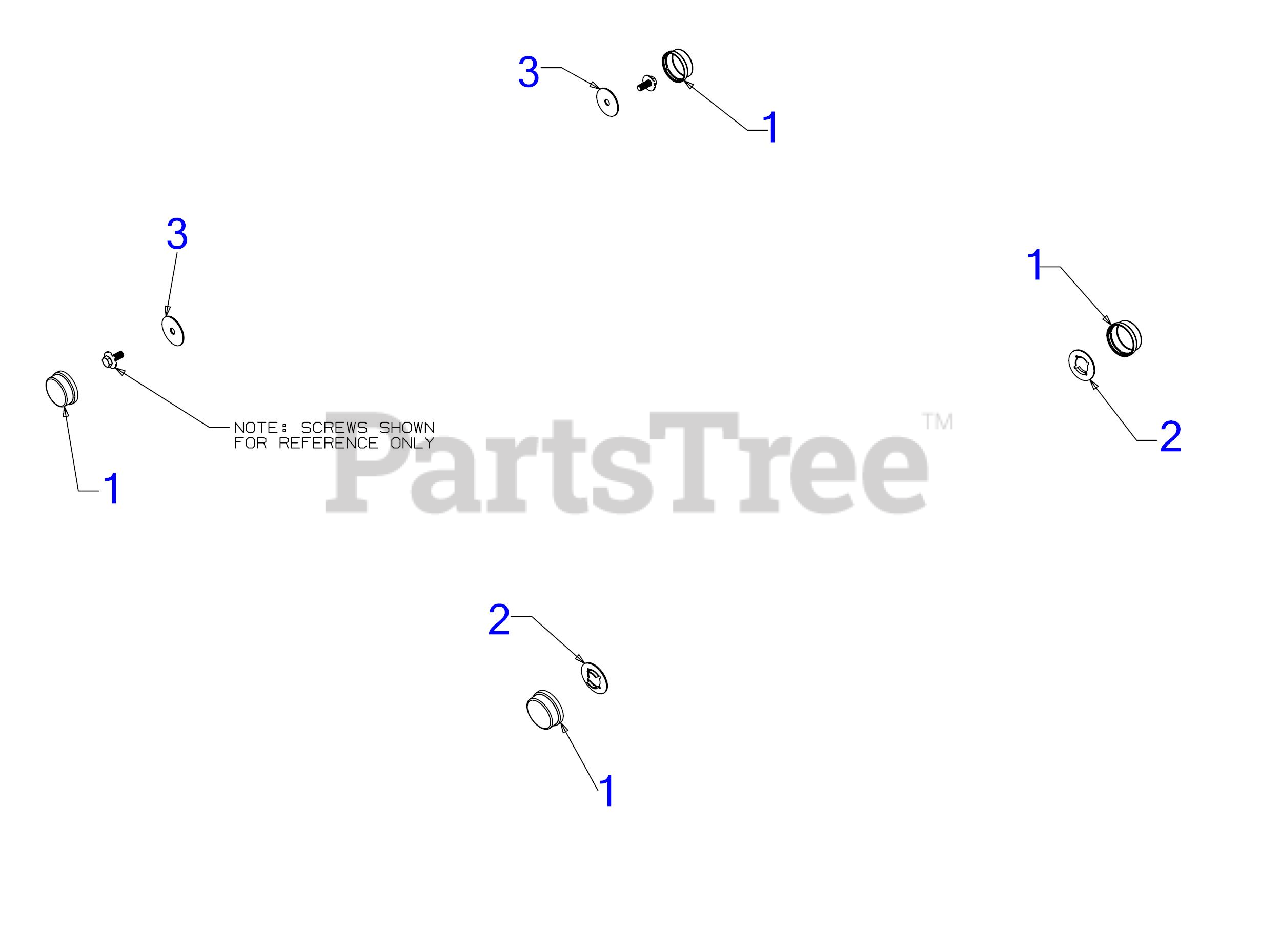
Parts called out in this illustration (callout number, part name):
1	HUB CAP-BLACK
2	FLAT WASHER .781 ID x1.590 OD
3	FLAT WASHER .350X1.59X.062
